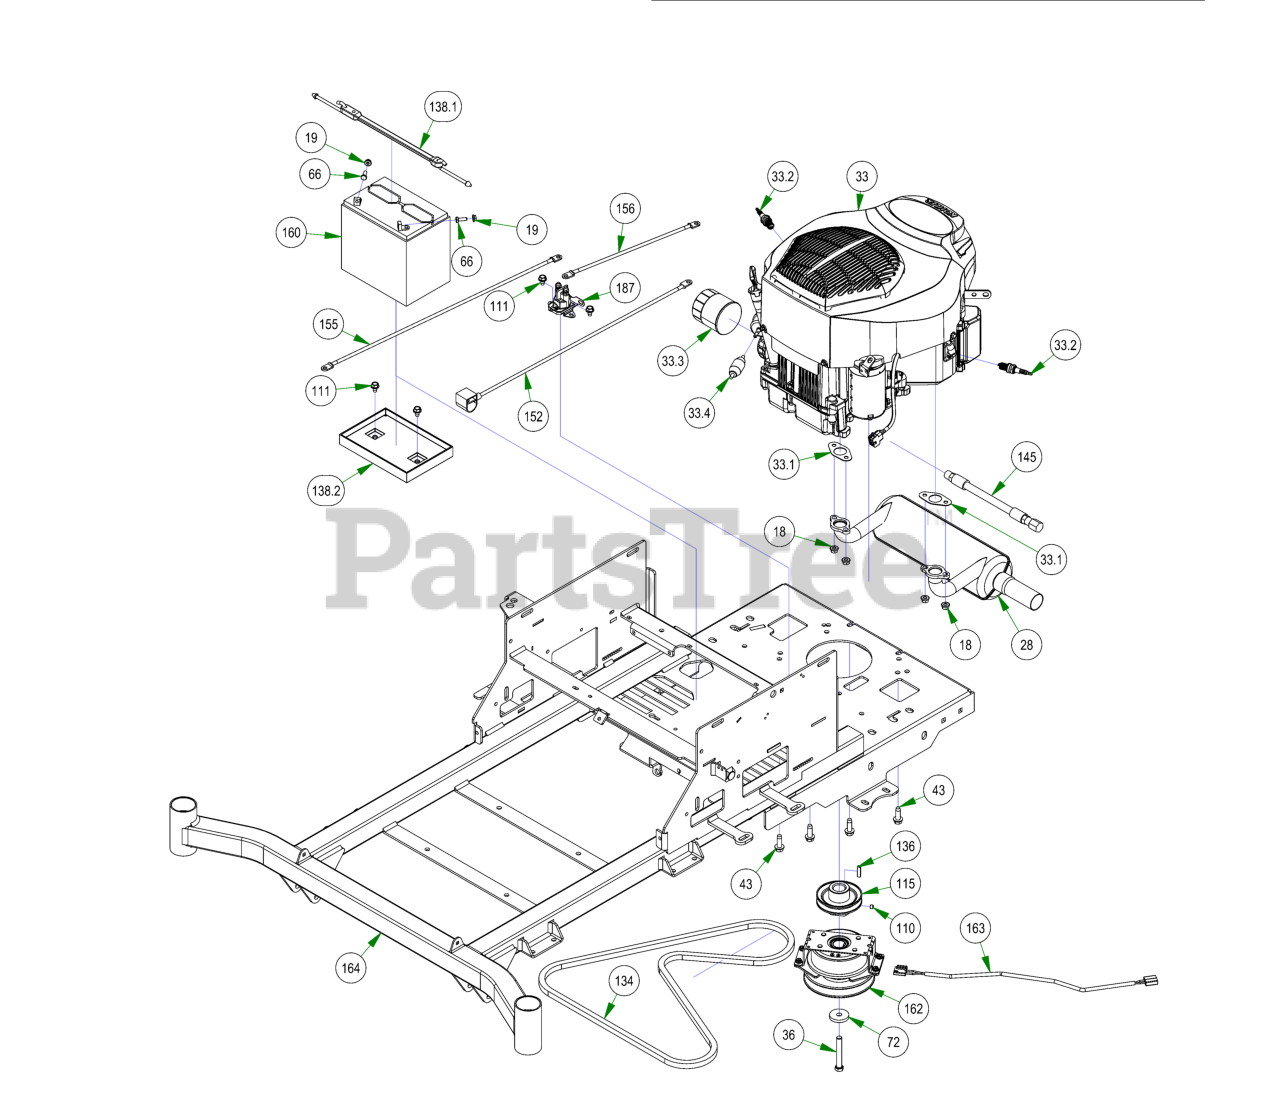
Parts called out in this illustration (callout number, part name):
18	M8 Nut Connects the 015-1012-00 and the 015-8240-00
19	1/4-20 HEX SERRATED FLANGE NUT HARD/ZINC
28	Kohler Muffler
33	25hp Kohler 2014 MZ-KT740-3048
33.1	Exhaust Gasket
33.2	Spark Plug
33.3	25 HP Kohler Oil Filter ZT?MZ
33.4	Universal Inline Fuel Filter
36	7/16-20x3” Hex Bolt GR 8 W/ Patch
43	3/8-16 X 1-1/8HEX WASHER UNSLOT SERRATED (TRI-LOB) TRS
66	1/4-20 X 3/4 HEX CAP SCREW (GR.5) ZINC
72	CLUTCH WASHER
110	5/16-24 X 1/4 SOCKET SET SCREW (CUP PT) PLAIN
111	5/16-18 X 1/2 HWH unslot (F) tcs zinc
115	3-3/4" Motor Pulley
136	1/4 X 1 SQ MACHINERY KEY 1018 STL PLN
138	2023 Battery Hold Down Assembly Strap
138.1	2023 Rubber Battery Hold Down Strap
138.2	Battery Tray
145	Oil drain Hose
152	24 inch Black Cable – MZ/ZT
155	24" Red Battery Cable
156	12 in red battery cable
160	SP-35 Battery
163	Clutch Pigtail
164	2023 MZ-Avenger 54-60 Frame - Painted
